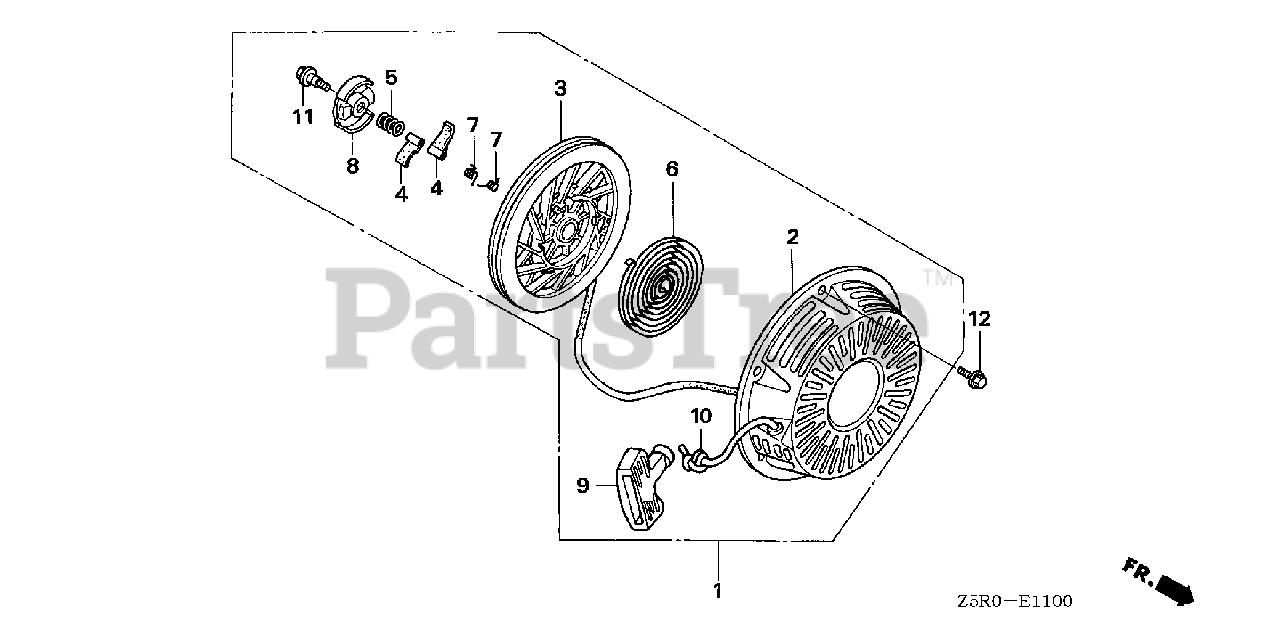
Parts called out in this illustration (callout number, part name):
1	STARTER ASSY., RECOIL *R280* (POWER RED)
2	CASE, RECOIL STARTER *R280* (POWER RED)
3	PULLEY, RECOIL STARTER
4	RATCHET, STARTER
5	SPRING, FRICTION
6	SPRING, STARTER RETURN
7	SPRING, RATCHET
8	RETAINER, SPRING
9	GRIP, STARTER
10	ROPE, RECOIL STARTER
11	SCREW, CENTER
12	BOLT, FLANGE (6X10)
